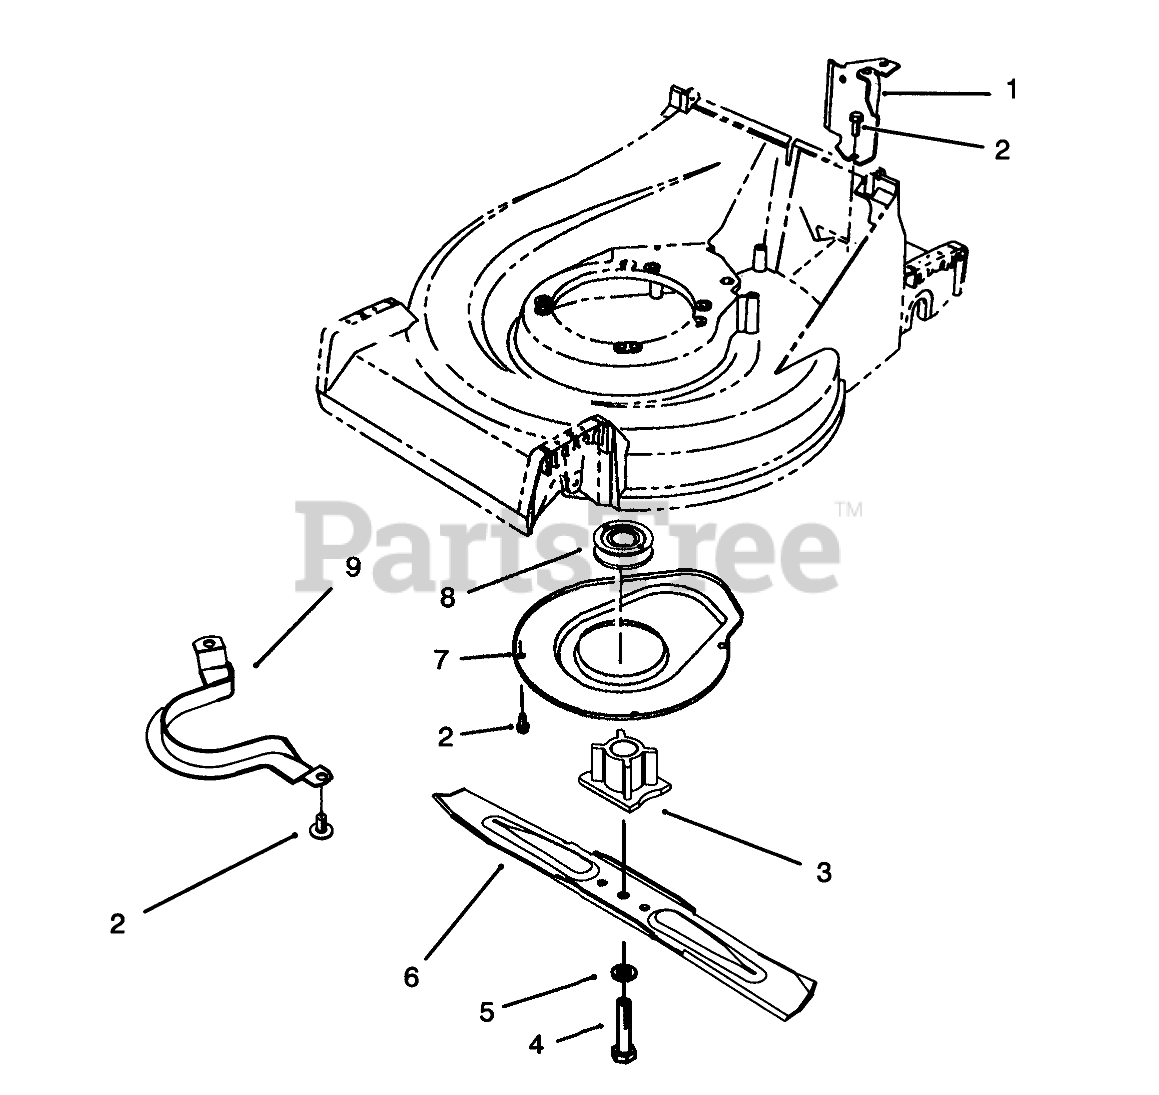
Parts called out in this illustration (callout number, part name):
1	Bracket-Cable Support
2	SCREW-HWHTF
3	BLADE RETAINER
4	SCREW-BLADE
5	WASHER-LOCK
6	Key
7	Cover
8	PULLEY-DRIVE, ZONE START
9	Guide-Belt
